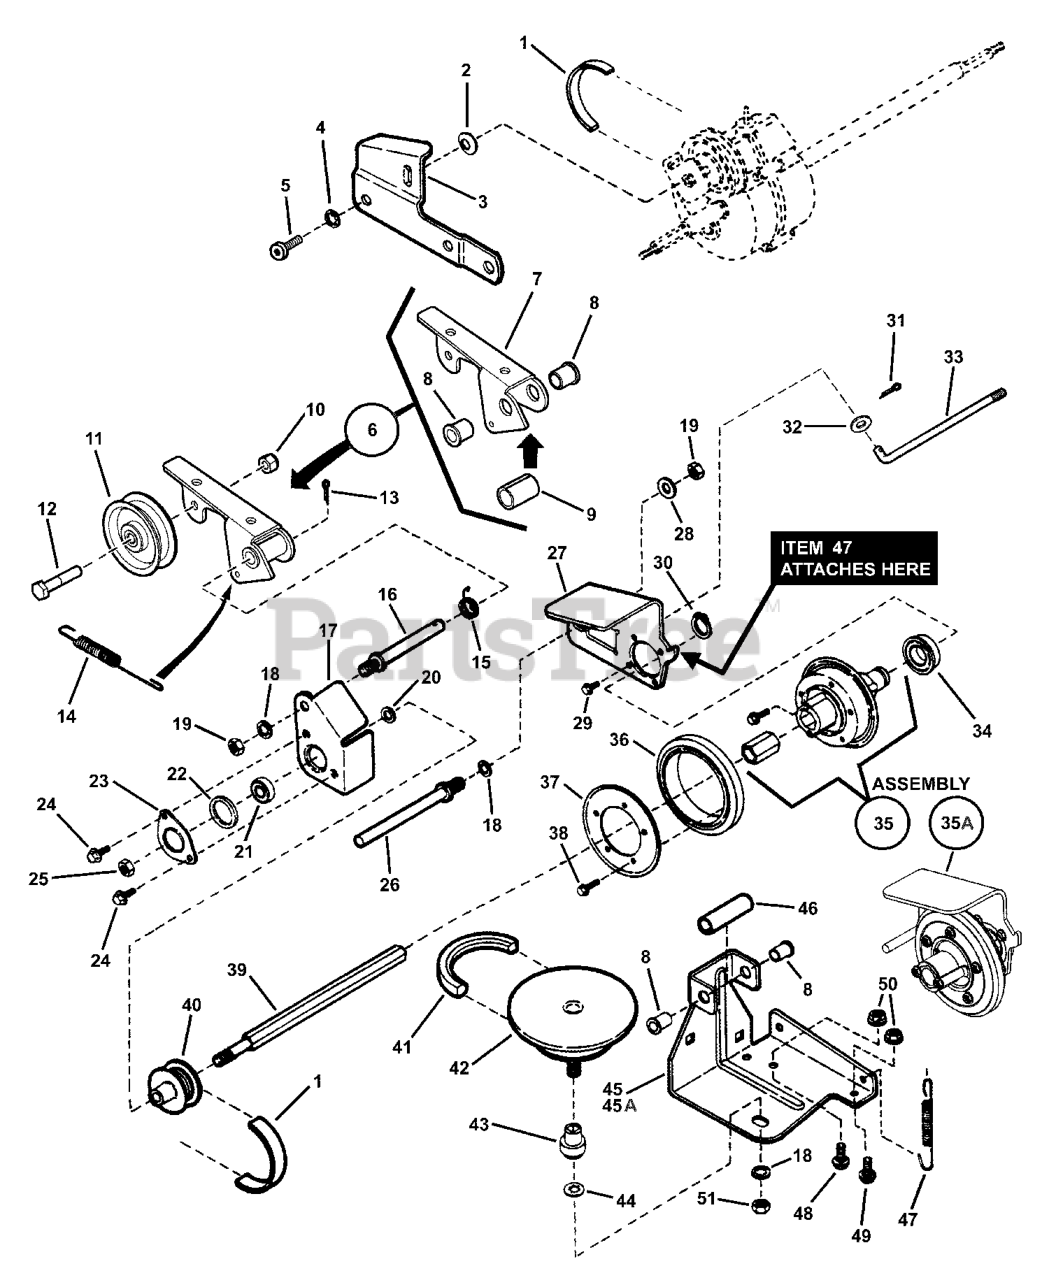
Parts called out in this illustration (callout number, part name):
1	BELT, Poly-V
2	WASHER, 44 x .78 x .025 Curved
3	LINK, Differential
4	WASHER, 5/16" Internal Tooth Lock
5	SCREW, 5/16-18 x 1/2" Pan Head Self-Tap (Torx)
6	ASSEMBLY, Idler Arm, Bushing & Spacer
7	ARM, Clutch Idler
8	BUSHING, Flange (Powdered Metal)
9	SPACER, Idler Arm
10	NUT, 1/4-28 Hex Top Lock
11	PULLEY, Idler
12	SCREW, 1/4-28 x 1-3/8" Hex Head Cap, GR 5
13	COTTER PIN, 3/32 x 1/2"
14	SPRING, Clutch- 21S
15	SPRING, Idler- Torsion
16	STUD, Idler (3/8-24 thread)
17	HOLDER, Bearing (Inner Half)
18	WASHER, 3/8" Internal Tooth Lock
19	NUT, 3/8-24 Hex
20	WASHER, 3/8" Flat
21	BALL BEARING, Spherical O.D., .38 I.D.
22	O-RING
23	HOLDER, Bearing (Outer Half)
24	SCREW, 1/4-20 x 1/2" Hex Flange Self-Tap
25	NUT, 3/8-24 Hex Center Lock, GR 5
26	GUIDE, Thrust Plate (3/8-24 thread)
27	THRUST PLATE, Short
28	WASHER, 3/8" Flat
29	SCREW, #10-32 x 1/4" Self-Tap Machine
30	RETAINING RING, .625 External
31	COTTER PIN, .06 x .50
32	WASHER, .28 x .63 x .06 Flat
33	LINK, Transfer (1/4-28 thread)
34	BALL BEARING, 3/4" Bore- Commercial
35	KIT, Driven Disc Bushing & Hub
35A	* ASSEMBLY, Driven Disc
36	DRIVEN RING
37	PLATE, Ring Retaining
38	SCREW, #10-24 x 1/2" Self-Tap Machine
39	SHAFT, Hex (3/8-24 thread, one end)
40	PULLEY, Poly-V (2.00" O. D.)
41	BELT, Engine Drive (Stretch)
42	ASSEMBLY, Steel Drive Disc
43	BUSHING, Powdered Metal
44	RETAINER, 5/16" Bolt
45	BRACKET, Deck, P21S
45A	ASSEMBLY, Deck Bracket (Incl. items 8, 45 & 46)
46	SPACER, .500 x .65 x 1.75
47	SPRING, Wheel Drive
48	BOLT, 5/16-18 x 1/2", Short Neck Carriage, GR 5
49	BOLT, 5/16-18 x 5/8" Short Neck Carriage, GR 5
50	NUT, 5/16-18 Hex Flange Lock GR 5
51	NUT, 3/8-16 Hex
